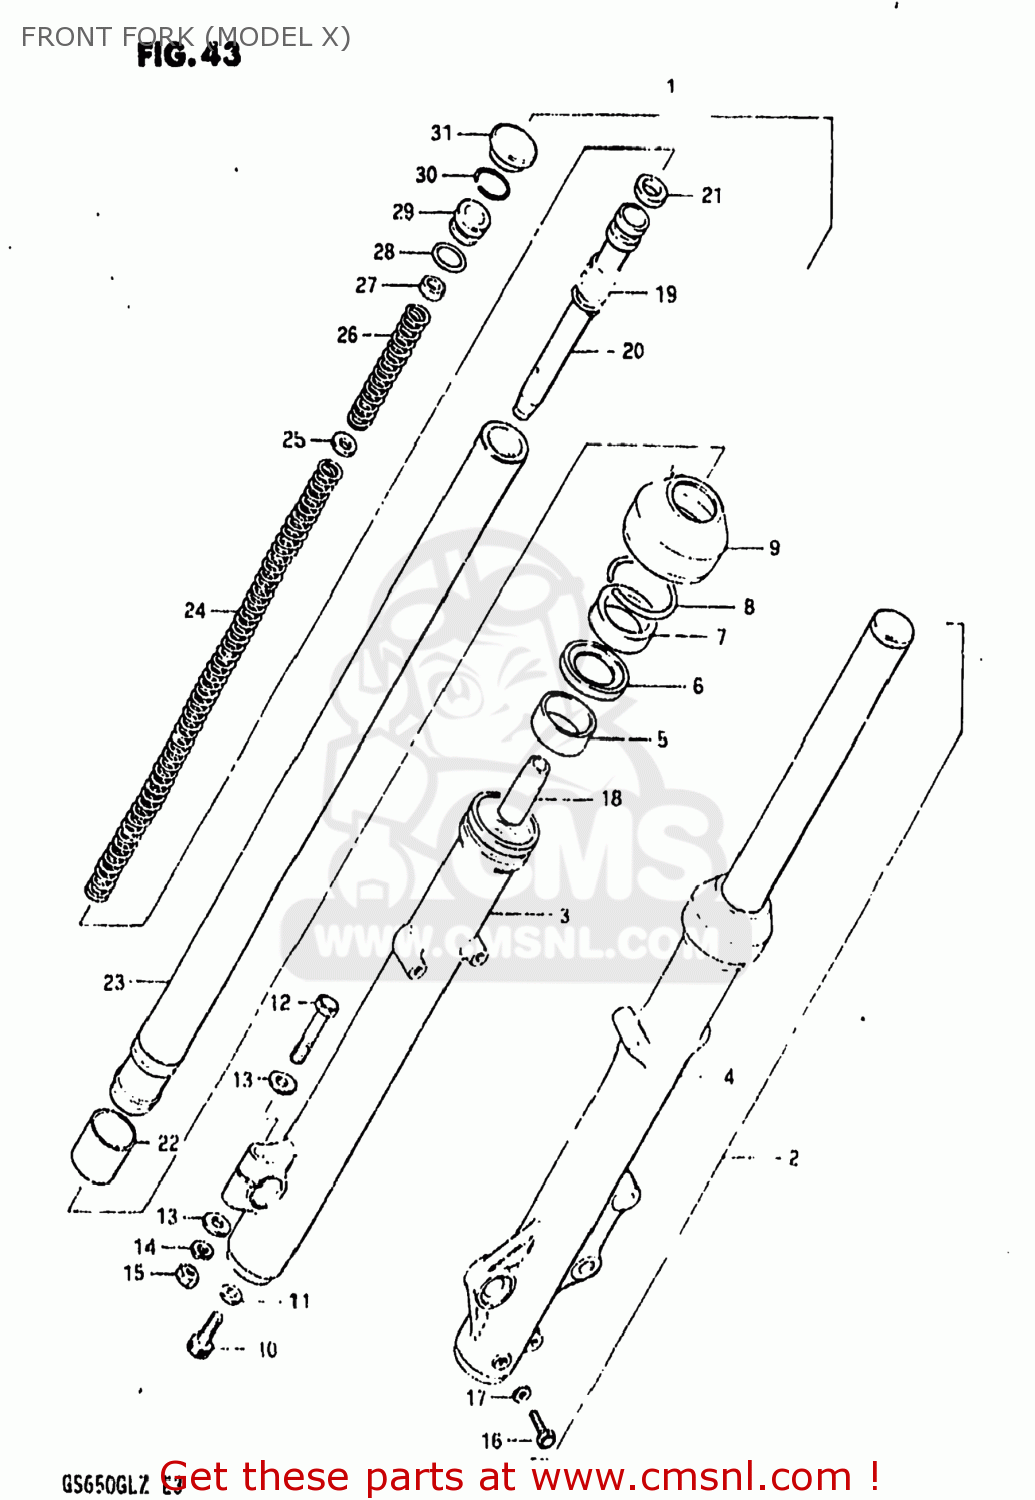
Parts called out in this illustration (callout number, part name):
1	DAMPER ASSEMBLY,RIGHT
2	DAMPER ASSEMBLY,LEFT
3	TUBE,OUTER,RIGHT
4	TUBE,OUTER,LEFT
5	BUSH,GUIDE
6	SPACER,SEAL
7	OIL SEAL,FRONT FORK
8	CIRCLIP,FORK OIL SEAL
9	BOOT
10	BOLT(8X27)
11	GASKET (NAS)
12	BOLT 8X50
13	WASHER
14	LOCK WASHER
15	NUT
16	BOLT(6X8)
17	GASKET,DRAIN,PLUG (NAS)
18	PIECE,OIL LOCK
19	SPRING,FORK REBOUND
20	CYLINDER,FRONT FORK
21	RING
22	PISTON
23	TUBE,FORK,INNER
24	SPRING,FRONT FORK MAIN,LOWER
25	WASHER,SPRING
26	SPRING,FRONT FORK,UPPER
27	SPACER,SPRING
28	O-RING
29	SPRING SEAT B
30	RING,STOPPER
31	CAP
